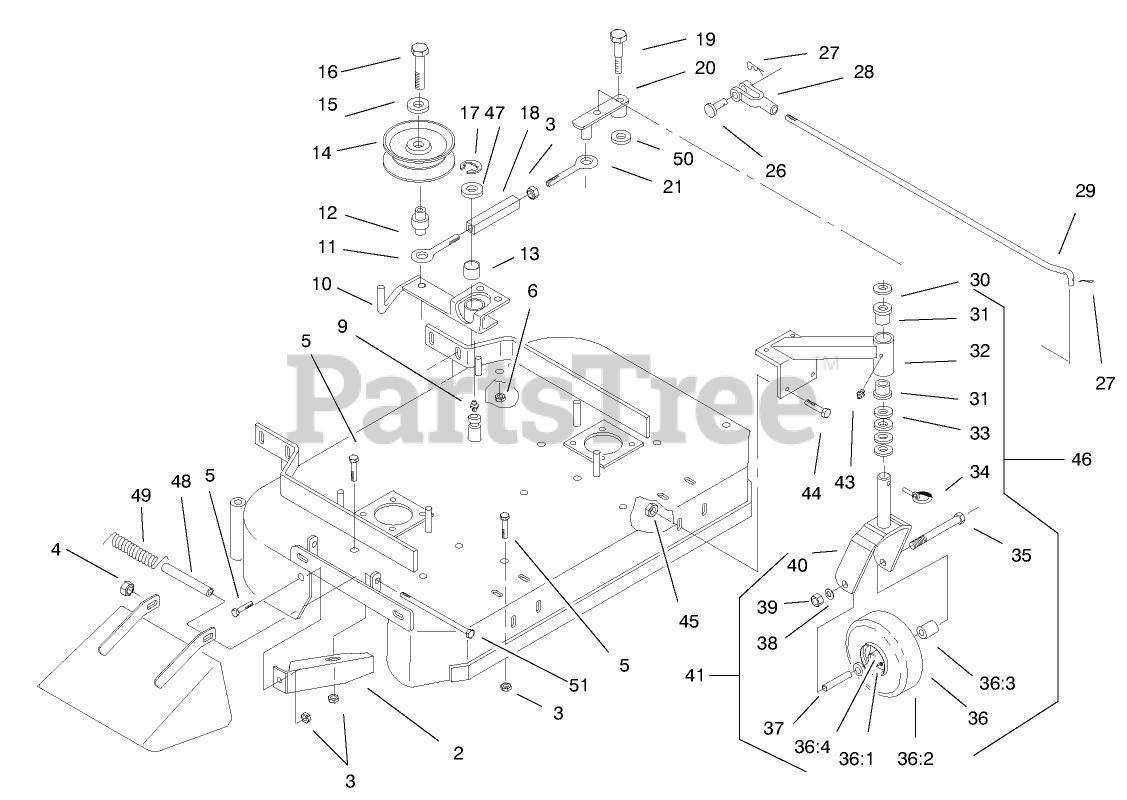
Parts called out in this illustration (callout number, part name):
2	Baffle
3	NUT-HF
4	NUT-LOCK, NI
5	Screw-HH
6	NUT-HF
9	FITTING-STRAIGHT
10	Engagement Arm w/Bushing
11	Eye Bolt
12	Bushing
13	Bearing
14	Pulley-Idler
15	WASHER-FLAT
16	Bolt-Whizlock
17	Ring-Snap
18	Turnbuckle Body
19	Bolt-Shoulder
20	Assist Arm ASM
21	Eye Bolt
26	Pin-Clevis
27	PIN-COTTER
28	Yoke
29	Linkage-Assist Arm
30	Washer
31	Bearing-Flanged
32	Support-Caster
33	Spacer
34	Pin
35	SCREW-HH
36	Tire and Wheel ASM
36:1	Wheel Hub ASM
36:2	Tire
36:3	Bearing
36:4	Bushing
37	Spacer
38	WASHER-LOCK
39	NUT-HH
40	Fork
41	Caster Wheel ASM (Incl. Ref. 36-40)
43	Zerk
44	SCREW-HH
45	NUT-FLANGE
46	Caster/Mount ASM (Incl. Ref. 31-40)
47	Spindle Washer
48	Spacer
49	Spring-Deflector
50	WASHER-THRUST
51	Screw-HH
